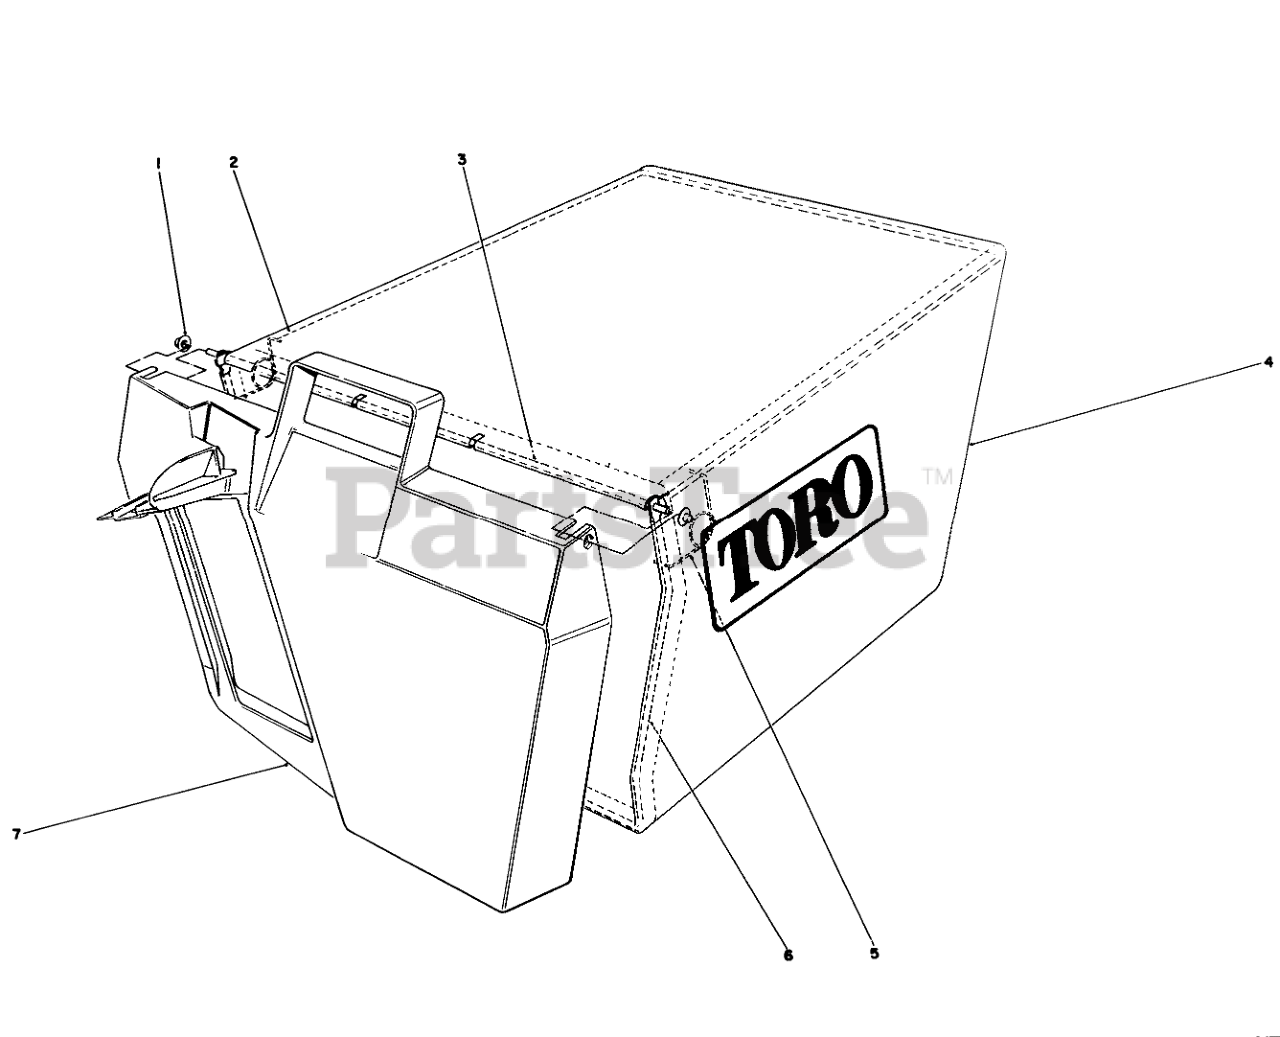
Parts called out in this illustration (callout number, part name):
1	NUT-PUSH
2	FRAME-BAG, UPPER
3	HINGE-DOOR, BAG
4	BAG-GRASS
5	SPRING
6	BAG FRAME
7	BAG DOOR
